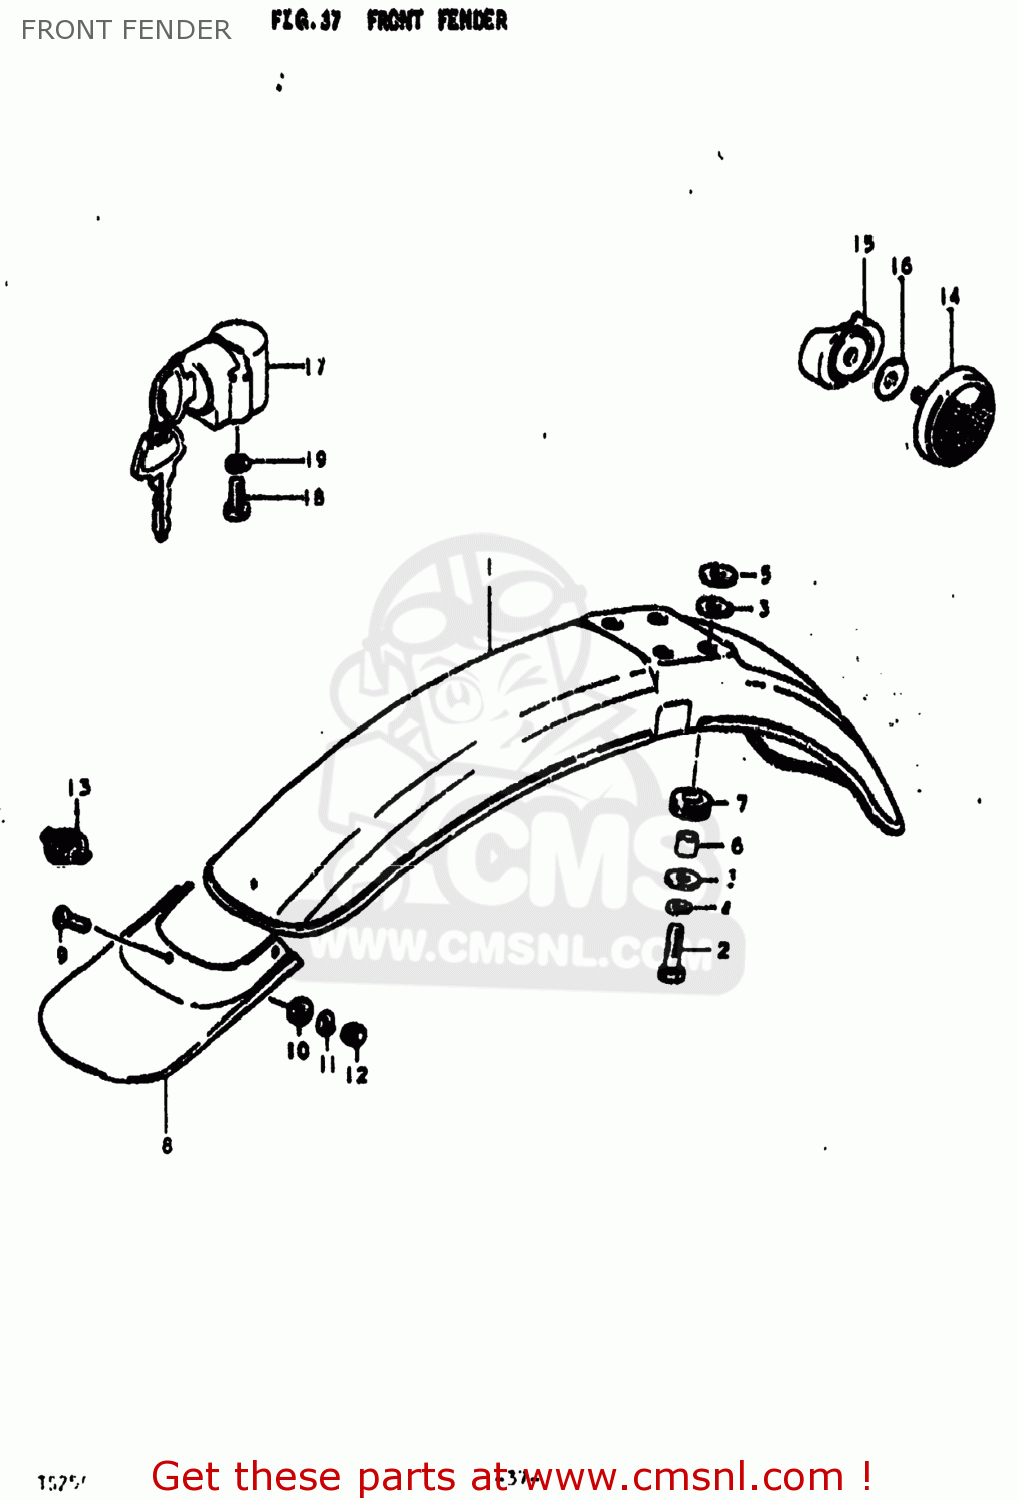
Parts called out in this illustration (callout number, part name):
1	FENDER,FRONT
2	BOLT
3	WASHER (6.5X24X1.2)
4	LOCK WASHER
5	SPACER (6.5X20X5)
6	SPACER (6.5X10.5X13.5)
7	CUSHION
8	MUD FLAP,FRONT FENDER
9	SCREW
10	WASHER
11	LOCK WASHER
12	NUT
14	REFLEX REFLECTOR ASSEMBLY
15	SPACER
16	WASHER (6.5X20X1.2)
17	LOCK ASSEMBLY,STEERING
18	SCREW
19	LOCK WASHER
